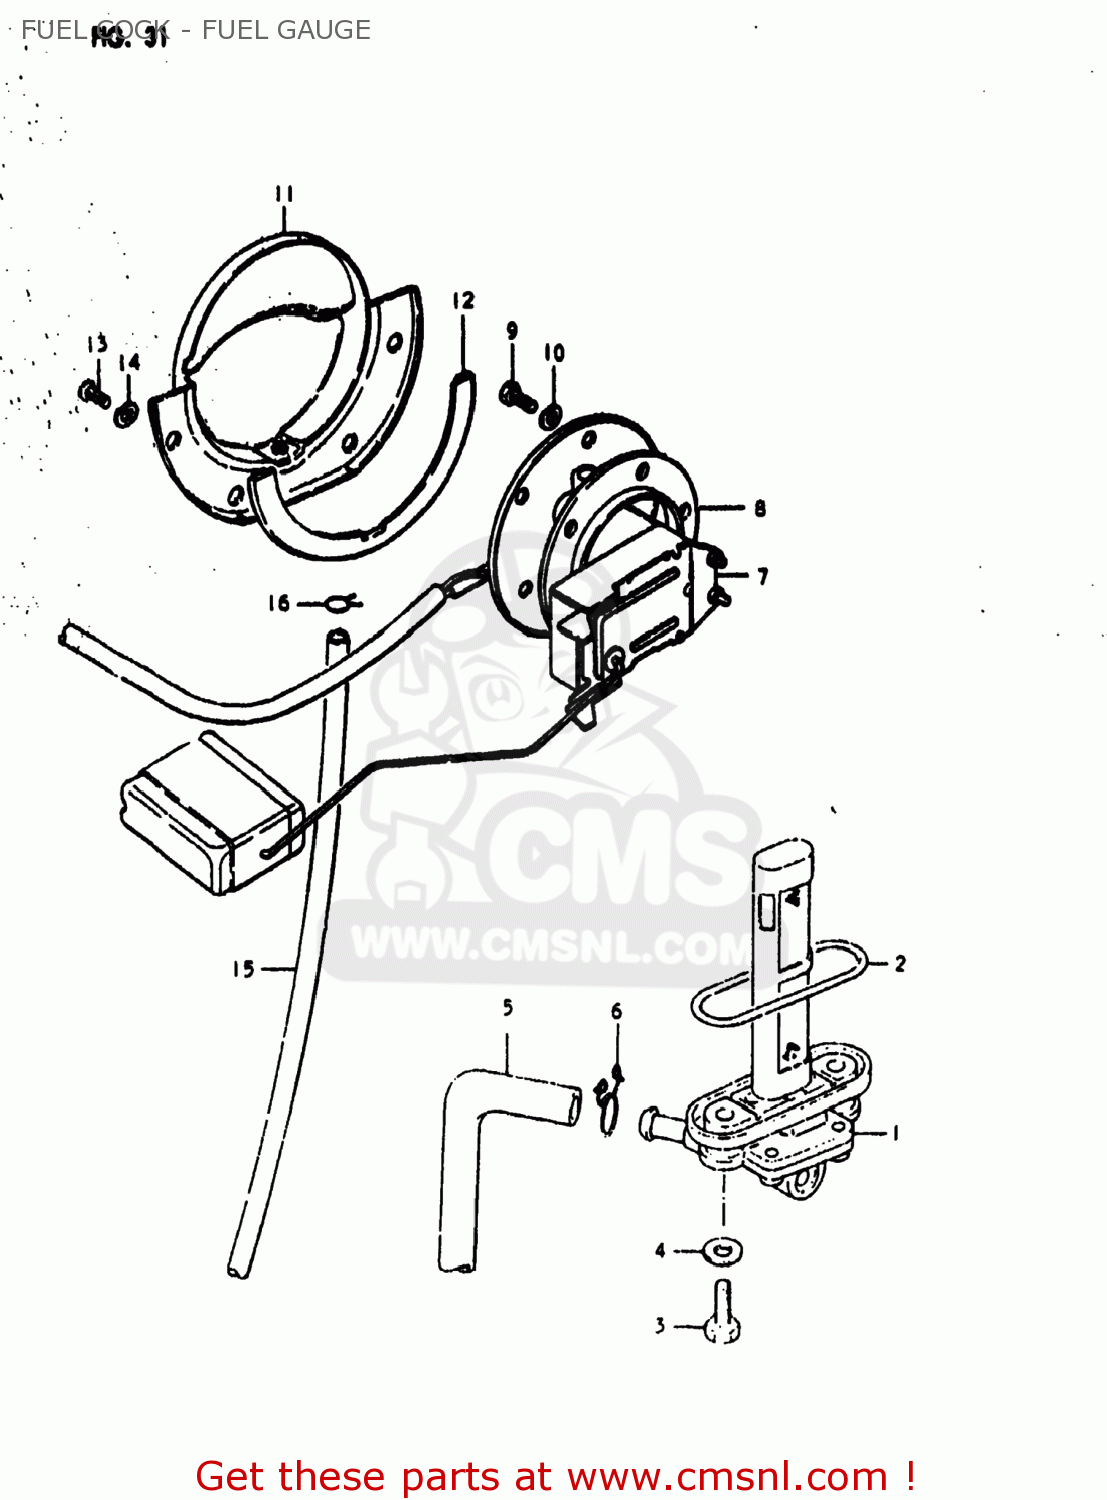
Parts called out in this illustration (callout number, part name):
1	COCK ASSY,FUEL
2	GASKET (NAS)
3	SCREW (6X25)
4	GASKET
5	HOSE
6	CLIP
7	GAUGE ASSEMBLY,FUEL LEVEL
8	GASKET,FUEL LEVEL GAUGE (NAS)
9	BOLT
10	LOCK WASHER
11	PLATE,FUEL DRAIN
12	GASKET,FUEL DRAIN PLATE (NAS)
13	SCREW
14	LOCK WASHER
15	HOSE,FUEL
16	CLIP
